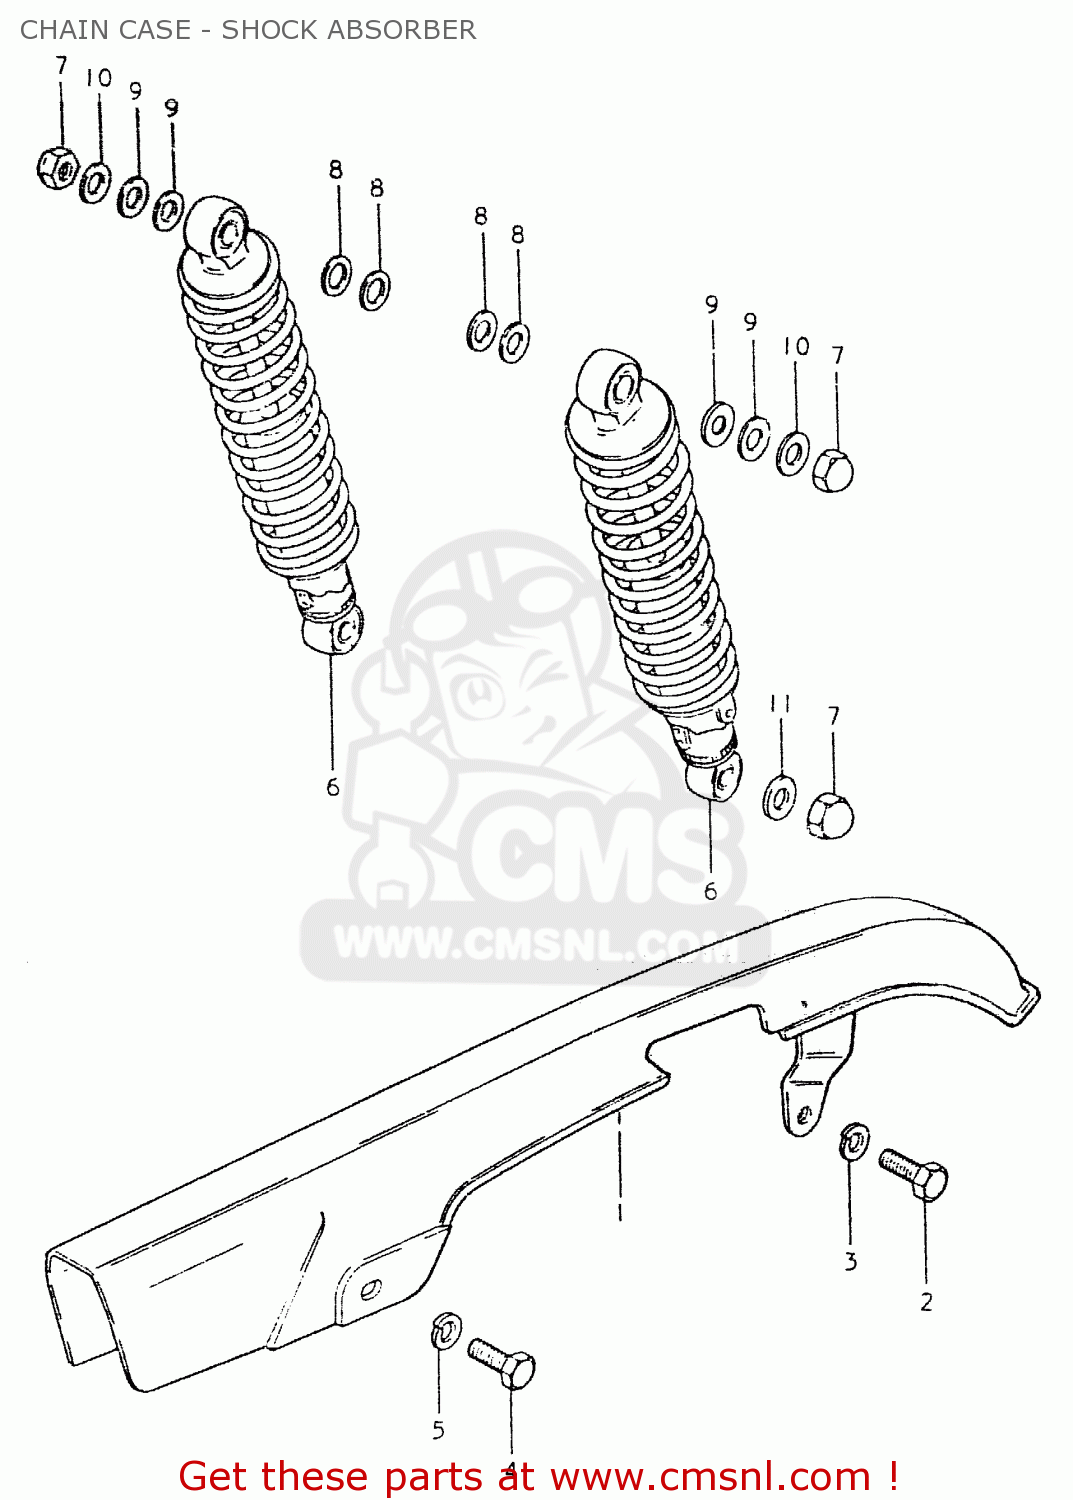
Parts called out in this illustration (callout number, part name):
1	CASE,CHAIN
2	BOLT
3	LOCK WASHER
4	BOLT
5	LOCK WASHER
6	ABSORBER ASSEMBLY,REAR SHOCK
7	NUT, LOWER LH
8	WASHER
9	WASHER
10	WASHER(10.5X24X3.2)
11	WASHER
